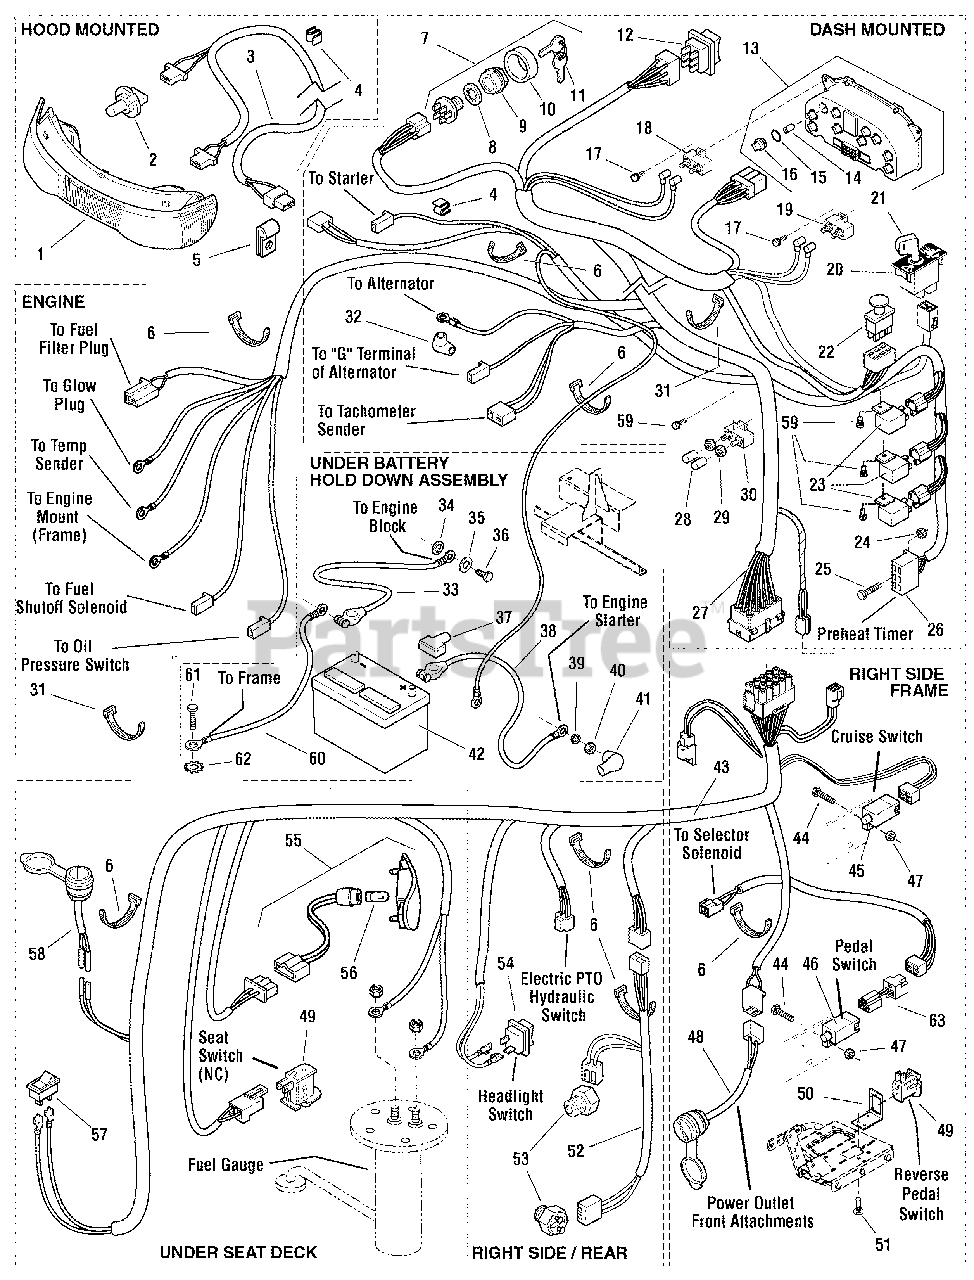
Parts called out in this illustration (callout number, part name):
2	BULB, Headlight, Halogen
3	HARNESS, Headlight
5	CLAMP, Wire 3/8 Diameter
6	TIE, Self Locking 7 in. Long
7	SWITCH ASSEMBLY, Ignition 5/8-32, 6 Pin INDAK
8	LOCKWASHER, Internal Tooth, 5/8, Thin
9	NUT, Hex Flange 5/8-32 Ignition Switch
10	COVER, Ignition Switch, Black
11	KEYS, Set of 2
12	SWITCH, Electric Lift, 6 Terminal
13	PANEL, Instrument
14	BULB, Instrument Panel
15	SEAL, Lamp Socket Plug
16	HOLDER, Bulb, Instrument Panel
17	SCREW, Hex Washer Head, Thread Cutting, #12-24 x 5/8
18	BREAKER, Circuit 12VOLT 10AMP
19	BREAKER, Circuit 12VOLT 20AMP with Tab
20	SWITCH, RMO Module Only
21	KEY, RMO Module, Plastic
22	SWITCH, PTO Push/Pull, Yellow
23	RELAY, 12VOLT 5 Blade
24	NUT, Hex Lock 10-24 with Nylock Insert, NC3B
25	SCREW, Round Head Phillips #10-24 x 3/4
26	RELAY, Glow Plug
27	HARNESS, Main Diesel
28	COVER, Wire, Black, Vinyl
29	NUT, Hex & Washer Assembly, KEPS
30	BREAKER, Circuit 30AMP 12VOLT
31	TIE, Self Locking 15 in. Long
32	COVER, Terminal Red
33	CABLE, Battery, # 4 x 10 in Long, Black
34	LOCKWASHER, External Tooth 5/16
35	WASHER, 3/8
36	CAPSCREW, Hex Head M08-1.25 x 16MM
37	INSULATOR, Battery Terminal, Red
38	CABLE, Battery, # 4 x 15 in Long, Red
39	LOCKWASHER, Spring 5/16
40	NUT, Hex Flange M08-1.25
41	BOOT, Cable Terminal
42	BATTERY, 12 Volt 6 Cell, 500 CCA
43	HARNESS, Rear
44	SCREW, Hew Washer Head Slot, #10-24 x 5/8
45	SWITCH, Push Button, Cuise Control
46	SWITCH, Push Button, Foot Pedal
47	NUT, Hex KEPS #10-24
48	HARNESS ASSEMBLY, Power Outlet
49	SWITCH, Push Button (No) Regent
50	BRACKET, Switch Mounting, Reverse Pedal
51	CAPSCREW, Hex Head Taptite, 1/4-20 x 3/8
52	HARNESS, Trasnmission, PTO Lights
53	SWITCH, Interlock Ball Check 5/16
54	SWITCH, Headlights, 2 Terminal
55	TAIL LIGHT ASSEMBLY
56	BULB, Tail Light
57	SWITCH, Rocker, Solenoid Select
58	OUTLET, 12 Volt
59	FASTENER, Panel
60	CABLE, 6 X 15 LG (2) Ring Terminals, Black
61	SCREW, Hex Washer HD, TAPTT 3/8-16 x 1
62	LOCKWASER, External Tooth, 3/8, Yellow
63	WIRING ASSEMBLY, All Conditions Shutdown
